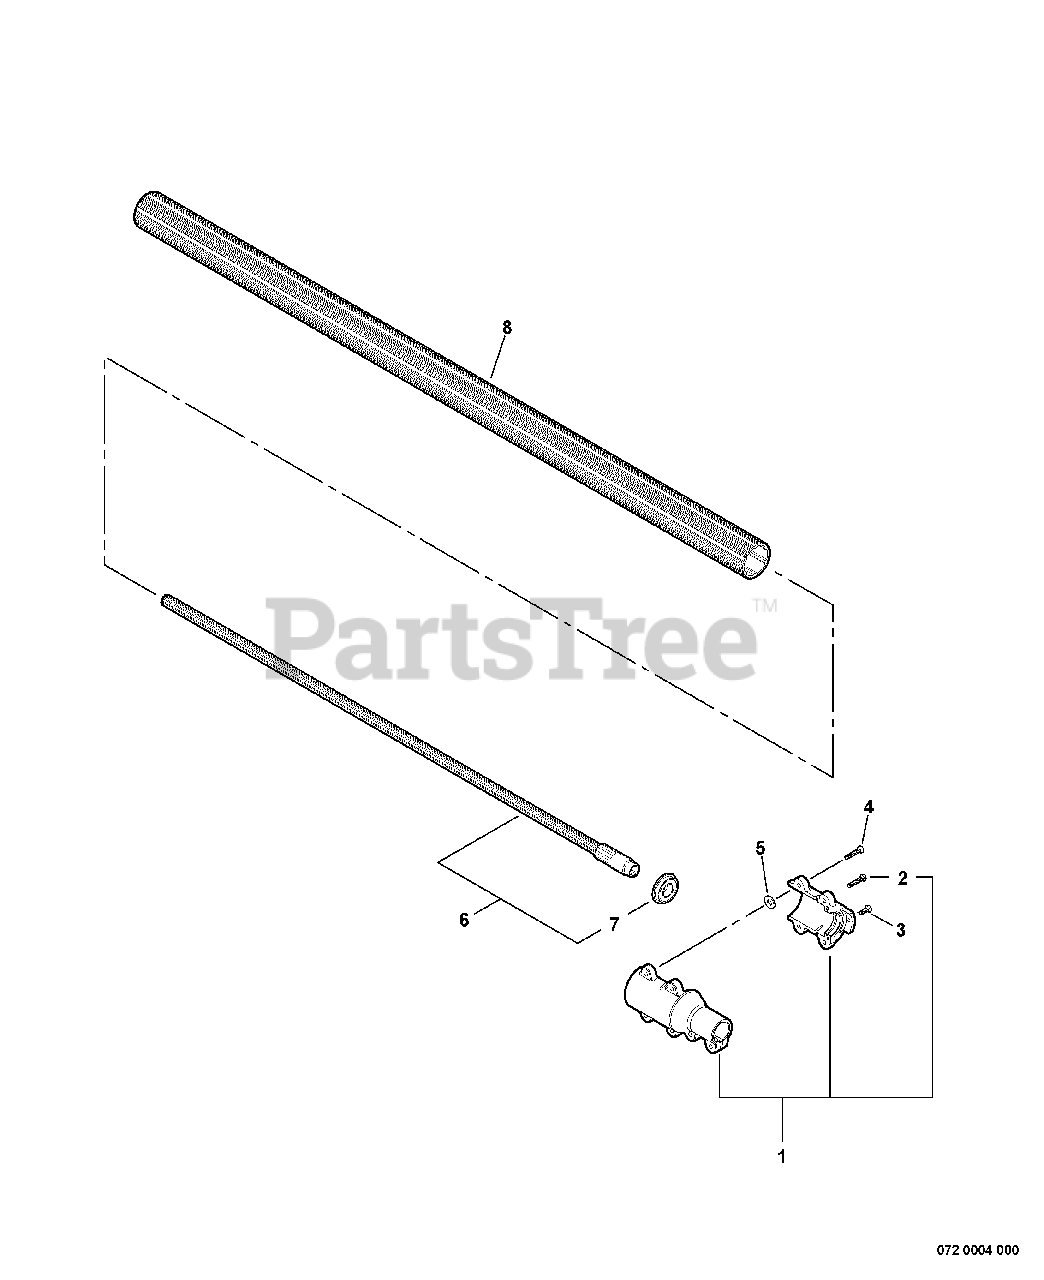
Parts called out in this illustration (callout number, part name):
1	COUPLING ASSY, LOWER
2	BOLT 5×20
3	BOLT 5×14
4	BOLT 5×20
5	WASHER 5
6	SHAFT ASSY, DRIVE
7	BEARING, BALL 15×32×9
8	PIPE, MAIN - ORANGE
